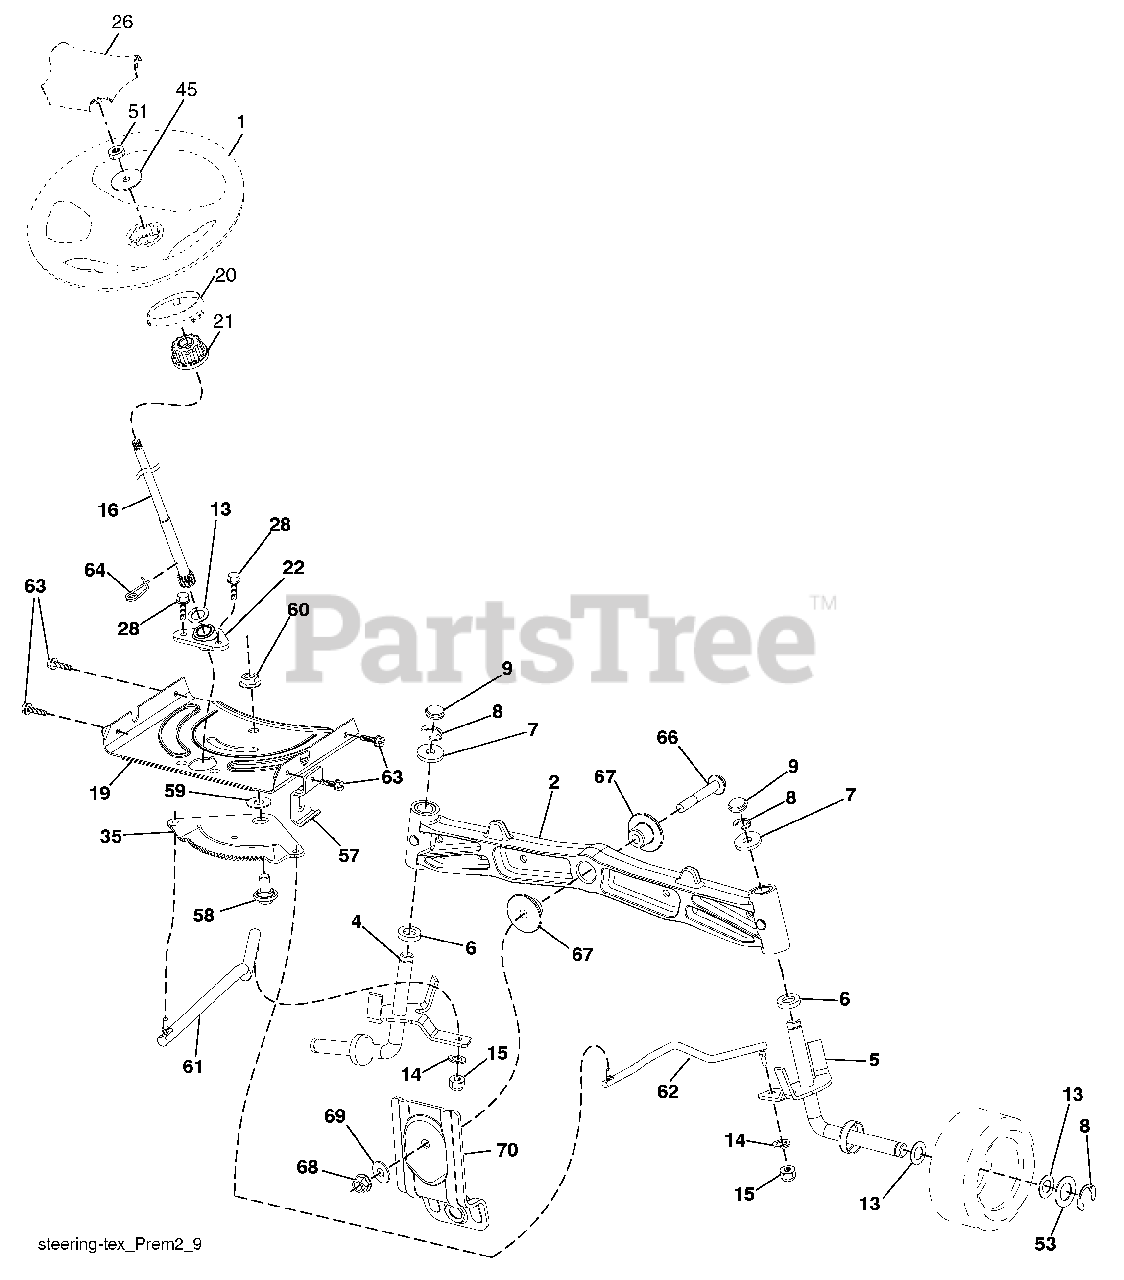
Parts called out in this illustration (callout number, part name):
1	Wheel, Steering
2	Axle Asm., Front
4	Spindle Asm., LH
5	Spindle Asm., RH
6	Bearing, Race Thrust Harden
7	Washer 25/32 x 1-5/8 x 16 Ga.
8	Ring, Klip #T5304-75
9	Cap, Spindle
13	Washer 25/32 x 1-1/4 x 16 Ga.
14	Washer, Lock Hvy Hlcl Spr 3/8
15	Nut, Crown Lock 3/8-24 unf
16	Shaft Steering
19	Plate Steering
20	Boot, Steering
21	Adapter, Wheel Steering
22	Strg. Supt. Lower
26	Insert, Wheel Steering
28	Screw 3/8-16 x 3/4
35	Gear, Sector Plate
45	Washer 9/16 x 2-3/8 x 12 Ga.
51	Nut Hex Jam Toplock 1/2-20 unf
53	Washer Hardened .793 x 1.637 x .060
57	Bracket Upstop
58	Bolt Shoulder Sector Pivot CFM
59	Washer Thrust Sector Steering
60	Nut Flange Lock 5/8-11
61	Draglink LH
62	Draglink, RH
63	Screw 5/16-18 x 3/4
64	Retainer Clip Spring Steering
66	Bolt Hex Fghd 7/16-14 x 3 Serr
67	Bushing PM Front Axle
68	Nut Lock Flange 7/16-14 Gr. 5
69	Washer 1.5 x .505 x .118
70	Bracket Deck Susp. Front
